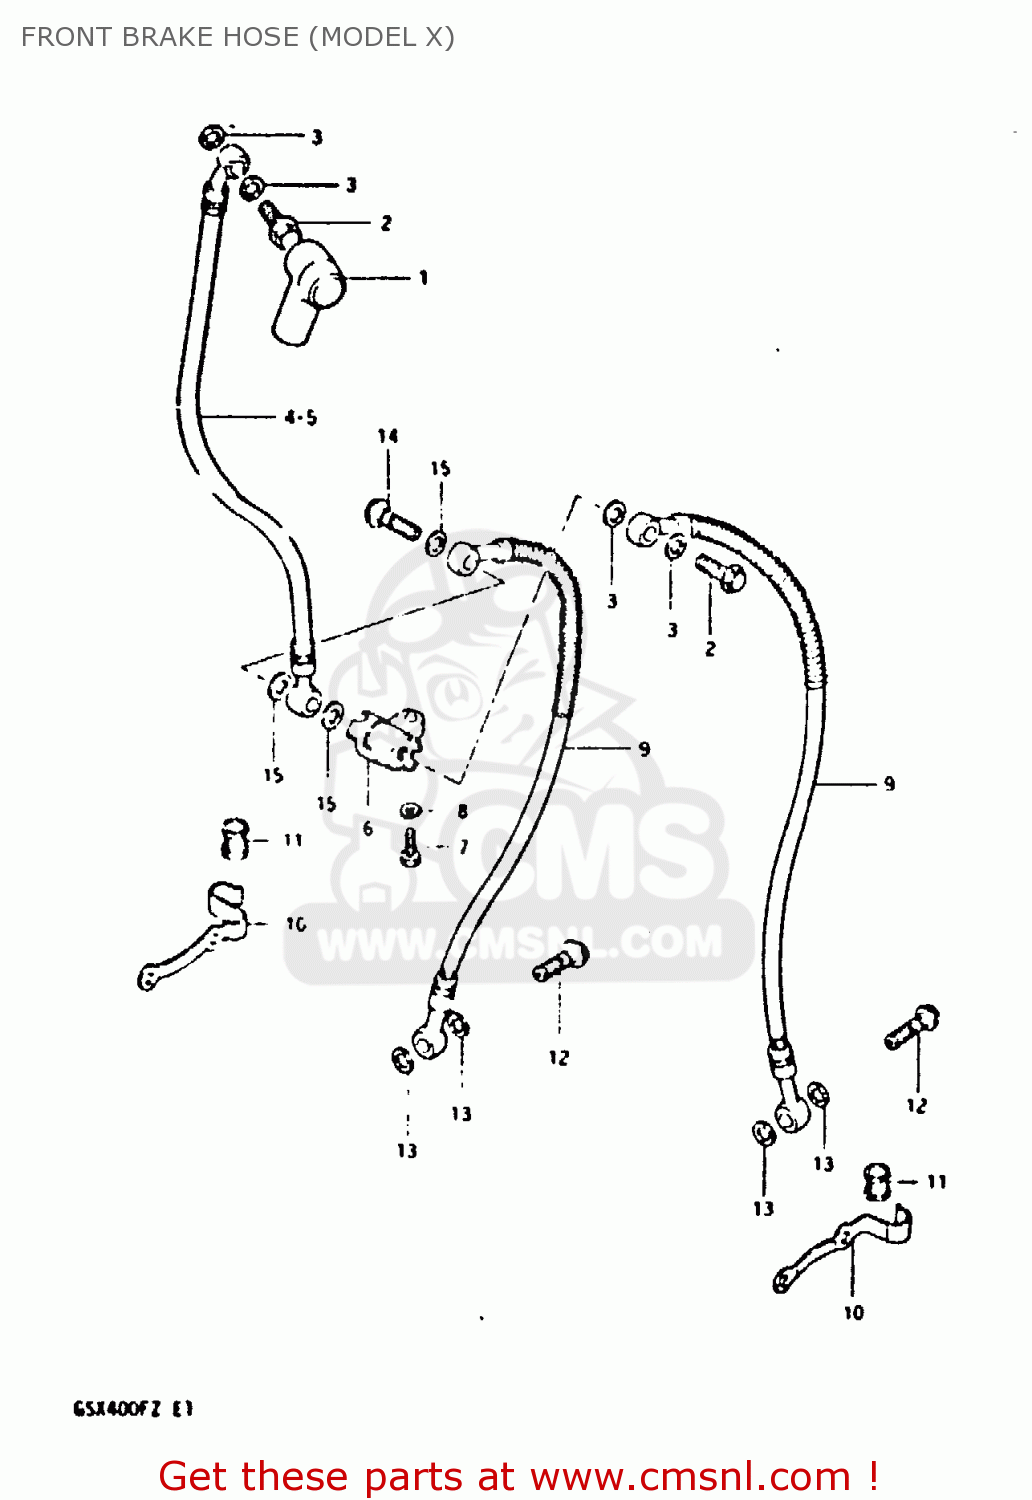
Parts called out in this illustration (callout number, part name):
1	BOOT,MASTER CYLINDER
2	BOLT,UNION
3	WASHER
4	HOSE, BRAKE NO.1 (FOR NEUTRAL HANDLEBAR)
5	HOSE,FRONT BRAKE
6	JOINT,BRAKE HOSE
7	BOLT
8	LOCK WASHER
9	HOSE,BRAKE NO.2
10	GUIDE,BRAKE HOSE NO.2
11	BUSH,BRAKE HOSE GUIDE,NO.2
12	BOLT,UNION
13	WASHER
14	BOLT,UNION
15	WASHER
